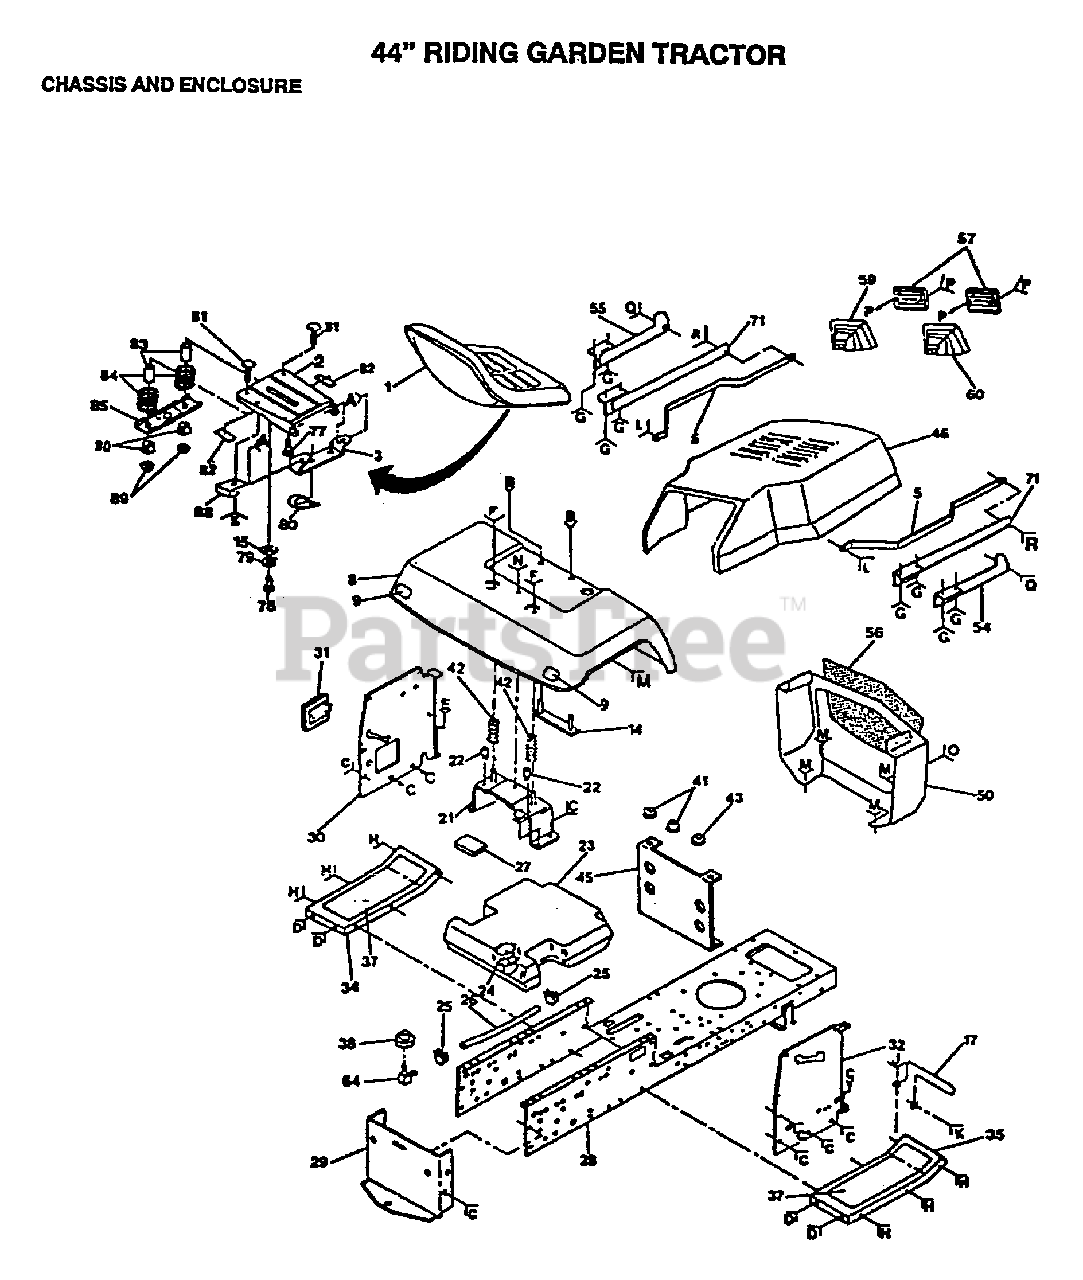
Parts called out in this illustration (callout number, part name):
9	REFLECTOR-TAIL YT
11	SCREW
12	WASHER
15	WASHER
17	GUARD MUFFLER HYT
18	NUT
20	WASHER
22	NUT-PUSH YT
25	HOSE CLAMP
27	PAD-SPACER LT
28	CHASSIS
31	COVER ACCESS
32	PANEL DASH RH YT
33	BOLT LT
36	BOLT
37	PAD FOOTREST T
38	BUSHING OUTLET T
39	LOCKWASHER
41	SNAP BUSHING T
42	SPRING COMPRESSIO
49	SCREW LT
54	STRAP ASSY T
55	STRAP ASSY T
56	SCREEN GRILL GTV
63	BOLT
64	FUEL TANK STEM GT
66	SCREW GTV
67	WASHER HYT
68	WASHER
69	SCREW
71	STRAP ASSY-REAR T
73	BOLT T
75	"BOLT,SHOULDER"
77	"BOLT,SHOULDER"
78	BOLT
79	LOCKWASHER
80	CLIP T
81	BOLT
82	STRIP FORM
83	SPACER SPLIT
84	SPRING COMPRESSED
85	BRKT SWITCH
87	"NUT,KEPS"
90	BUSHING
